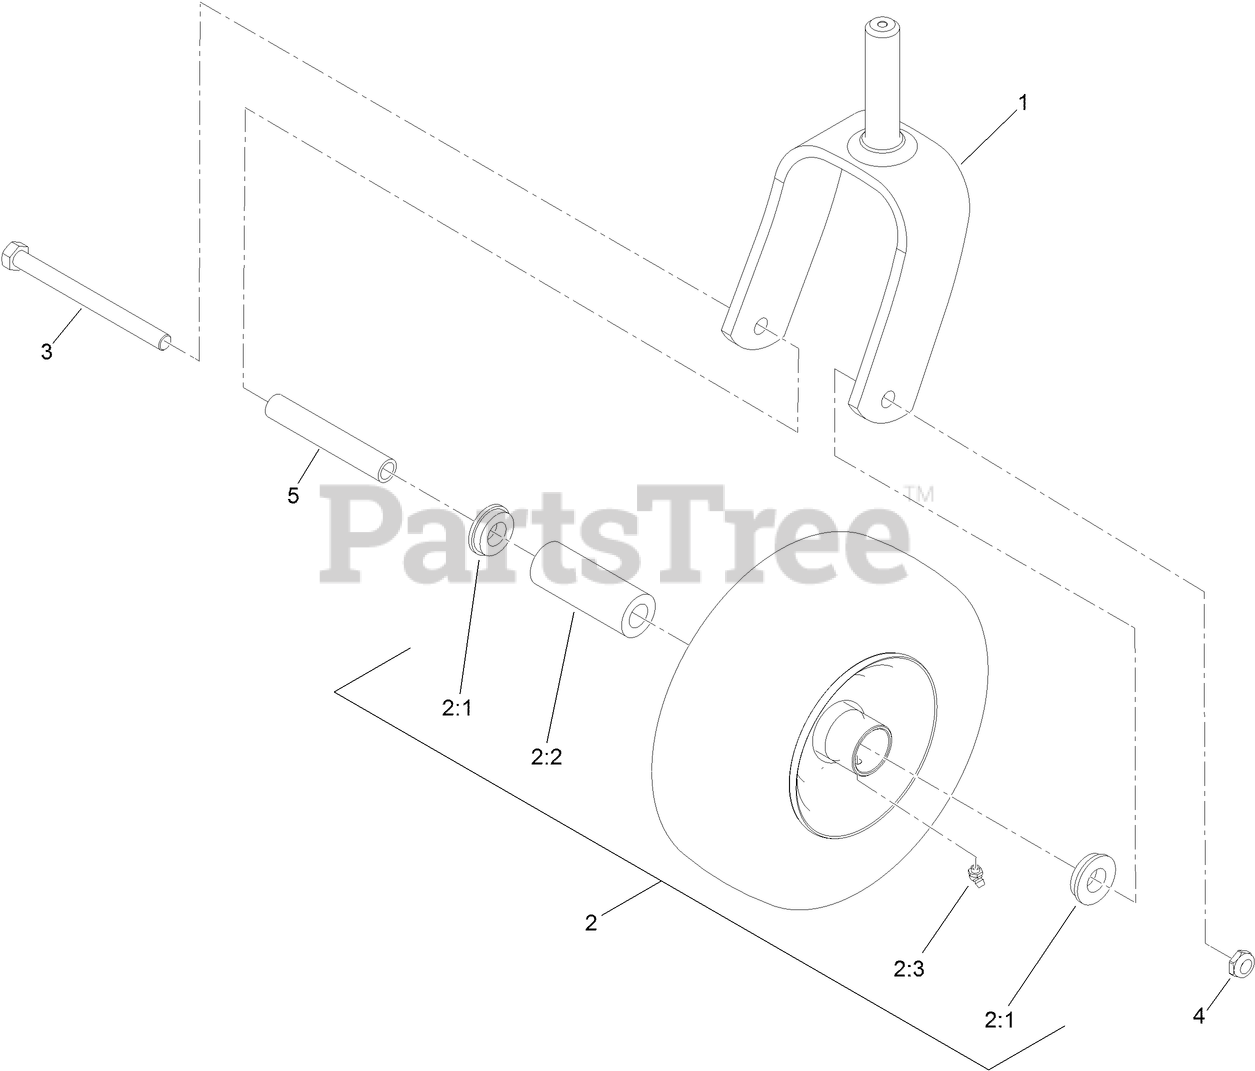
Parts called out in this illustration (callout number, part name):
1	FORK-CASTER
2	WHEEL AND TIRE ASM
2:1	BUSHING
2:2	BEARING
2:3	FITTING-GREASE
3	SCREW-HH
4	NUT-HEX
5	SPACER
